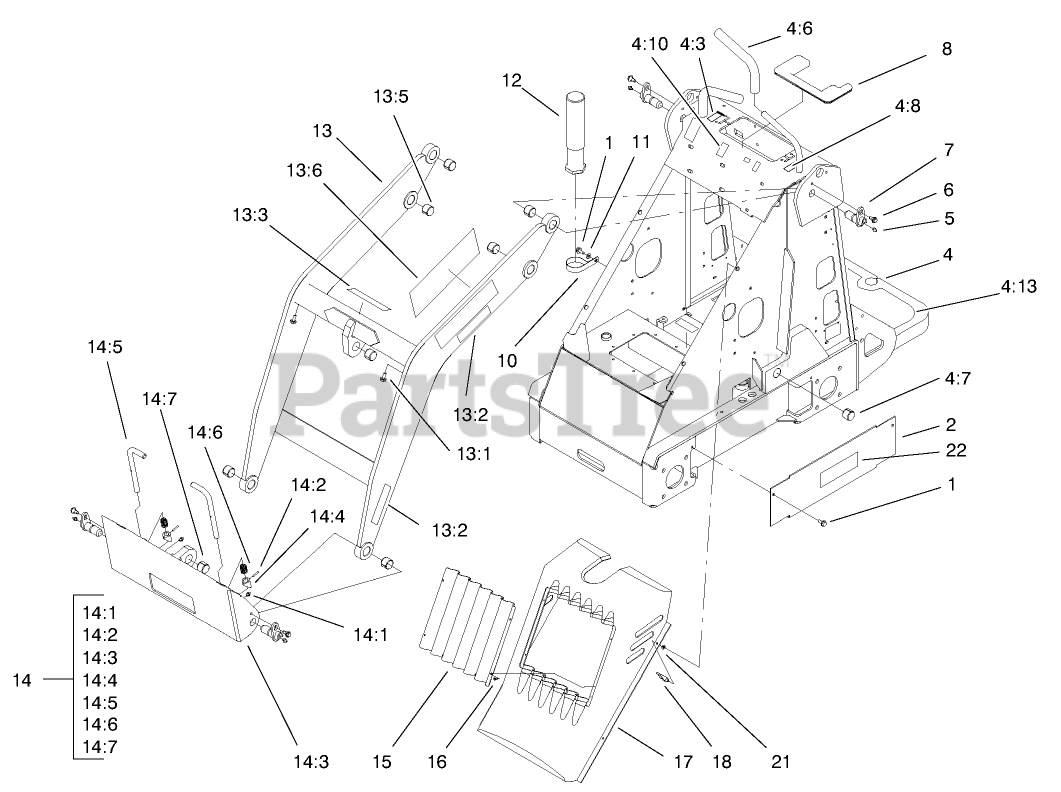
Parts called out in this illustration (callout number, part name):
1	SCREW-HWHTF
2	Cover-Hose
4	Frame & Decal ASM
4:3	DECAL-CHOKE
4:6	GRIP-CUSHION
4:7	BUSHING-TENSION
4:8	DECAL-THROTTLE
4:10	DECAL-SELECTOR
4:13	TREAD-FOOT
5	FITTING-GREASE
6	BOLT-SHOULDER
7	PIN-PIVOT
8	COVER-VALVE
10	CLAMP-R
11	WASHER-PLAIN
12	TUBE-MANUAL
13	LOADER ASM
13:1	SCREW-HWHTF
13:2	DECAL-PINCH
13:3	DECAL-CAUTION
13:5	BUSHING-TENSION
13:6	DECAL-DANGER
14	QUICK ATTACH ASM
14:1	FITTING-GREASE
14:2	PIN-SPECIAL
14:3	MOUNT-ATTACH, QUICK
14:4	CAM-ATTACH, QUICK
14:6	SPRING-COMPRESSION
14:7	BUSHING-TENSION
15	Grille-Screen
16	SCREW-PPH
17	COVER-HOOD
18	LATCH-SWELL
21	WASHER
22	DECAL-4-PAW
